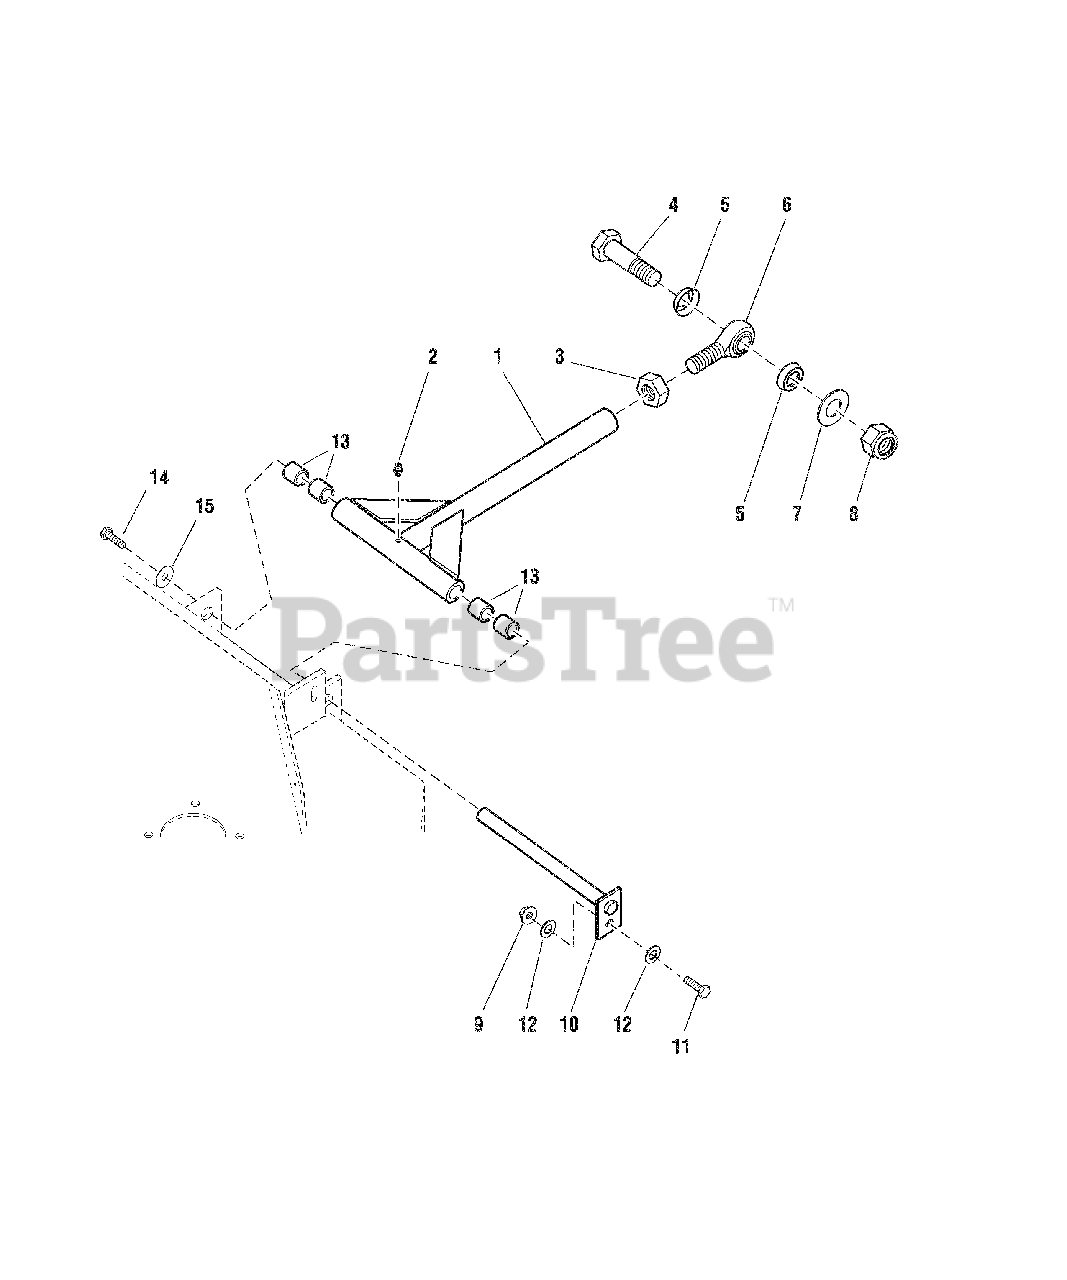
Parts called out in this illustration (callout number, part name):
1	PUSHER BAR ASSEMBLY
2	GREASE FITTING
3	NUT, 3/4-16 Hex Jam
4	BOLT, 3/4-16 x 3
5	ROD END SEAL
6	BALL JOINT, 3/4-16 Male
7	WASHER, 3/4" SAE
8	NUT, 3/4-16 Hex Nylon Lock
9	NUT, 3/8-16 Hex Nylon Lock
10	WELD, DECK MOUNT SHAF
11	BOLT, 3/8-16 x 1-1/4
12	WASHER, 3/8" SAE
14	BOLT, 3/8-16 X 1 GD5 YZ
15	WASHER, .390 X 1.50 X .109 YZ
